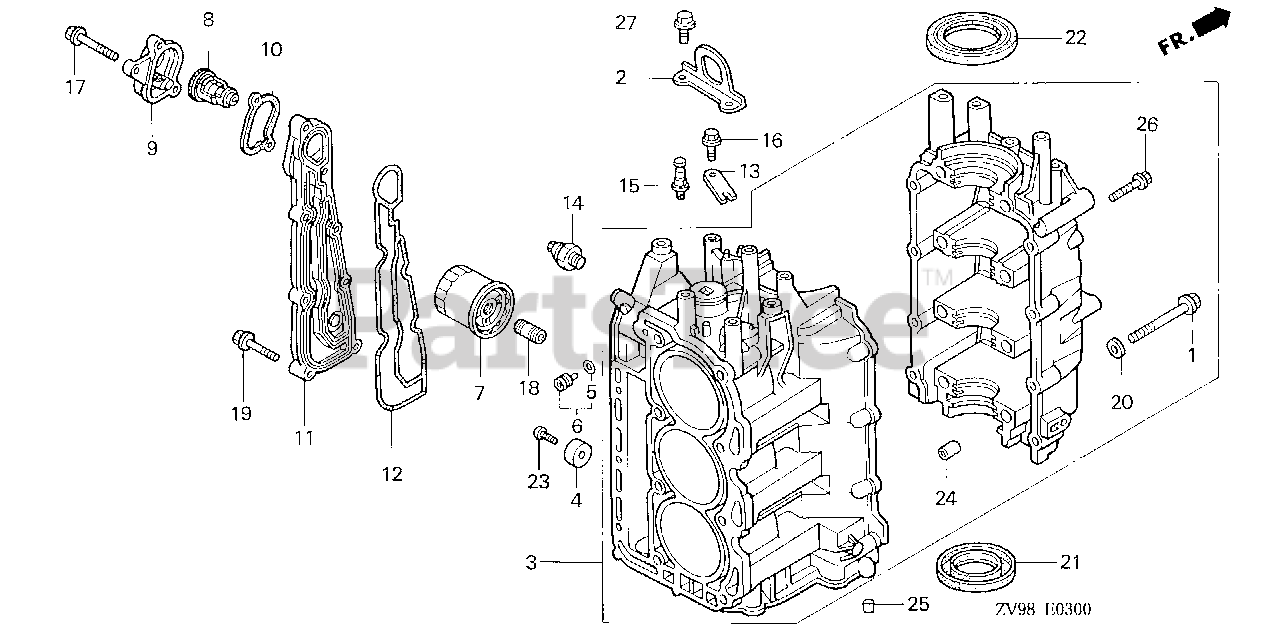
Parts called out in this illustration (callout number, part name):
1	BOLT, FLANGE (8X85)
2	HANGER, ENGINE
3	BLOCK ASSY., CYLINDER *NH8* (DARK GRAY)
4	METAL, ANODE
5	O-RING (4.8X1.9)
6	ORIFICE ASSY., OIL PASSAGE
7	FILTER, OIL (DENSO)
8	THERMOSTAT ASSY.
9	COVER, THERMOSTAT *NH8* (DARK GRAY)
10	GASKET, THERMOSTAT COVER
11	COVER, WATER JACKET *NH8* (DARK GRAY)
12	GASKET, WATER JACKET COVER
13	PLATE, SHIFT SHAFT
14	SWITCH ASSY., OIL PRESSURE (DENSO)
15	BOLT, TIMING BELT ADJUSTING SPRING
16	BOLT, FLANGE (6X12)
17	BOLT, FLANGE (6X35)
18	HOLDER, OIL FILTER
19	BOLT, FLANGE (6X22) (CT200)
20	WASHER, PLAIN (8MM)
21	OIL SEAL (35X52X8)
22	OIL SEAL (44.5X60.5X8) (NOK)
23	SCREW, PAN (6X18)
24	PIN, DOWEL (10X12)
25	PIN, DOWEL (6X10)
26	BOLT, FLANGE (6X40)
27	BOLT, FLANGE (8X18)
